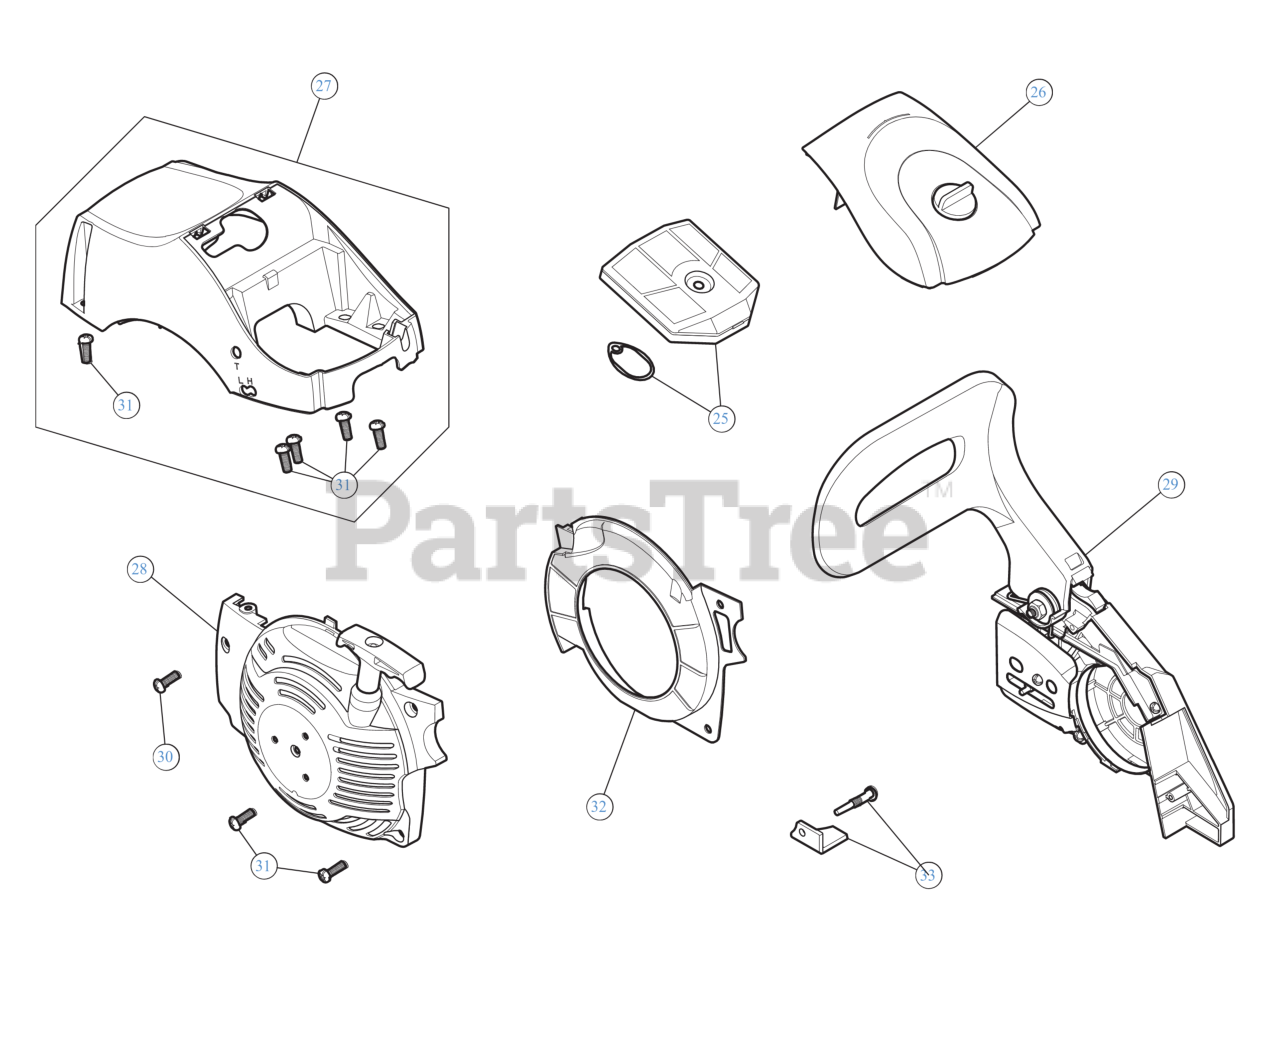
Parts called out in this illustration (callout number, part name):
25	AIR FILTER
26	AIR FILTER COVER
27	CYLINDER COVER
28	STARTER HOUSING
29	CHAINSAW BRAKE
32	BAFFLE
33	CHAIN CATCHER
